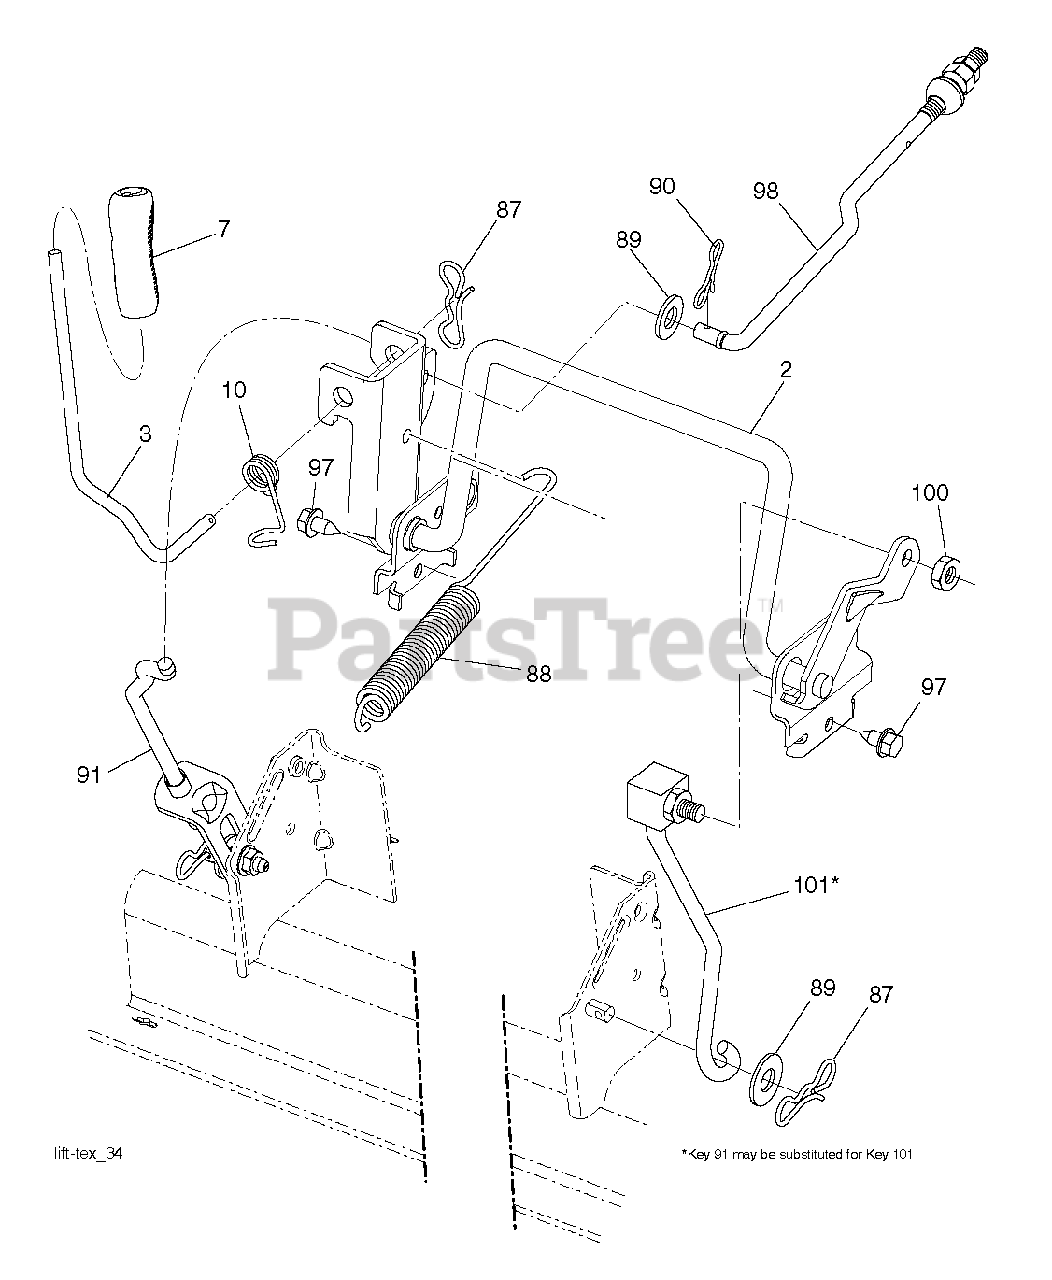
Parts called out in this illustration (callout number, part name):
2	SHAFT LIFT DECK WELD
3	LEVER.LIFT.HANDLE.LT
7	GRIP.HANDLE.LIFT.PVC.BLACK
10	SPRING.TORSION.LIFT.HANDLE
87	PIN.COTTER.7/16.BOW TI.
88	SPRING.DK.LIFT.97/107.TXCRDII
89	WASHER.CLEAR.ZINC
90	PIN.COTTER.5/16.BOW TI
91	LINK.ASM.LIFT.REAR
98	LINK.ASM.SUSP.FRONT.MW
100	LOCKNUT
101	LINK.ASM.LIFT.FIXE.38/42/46"
